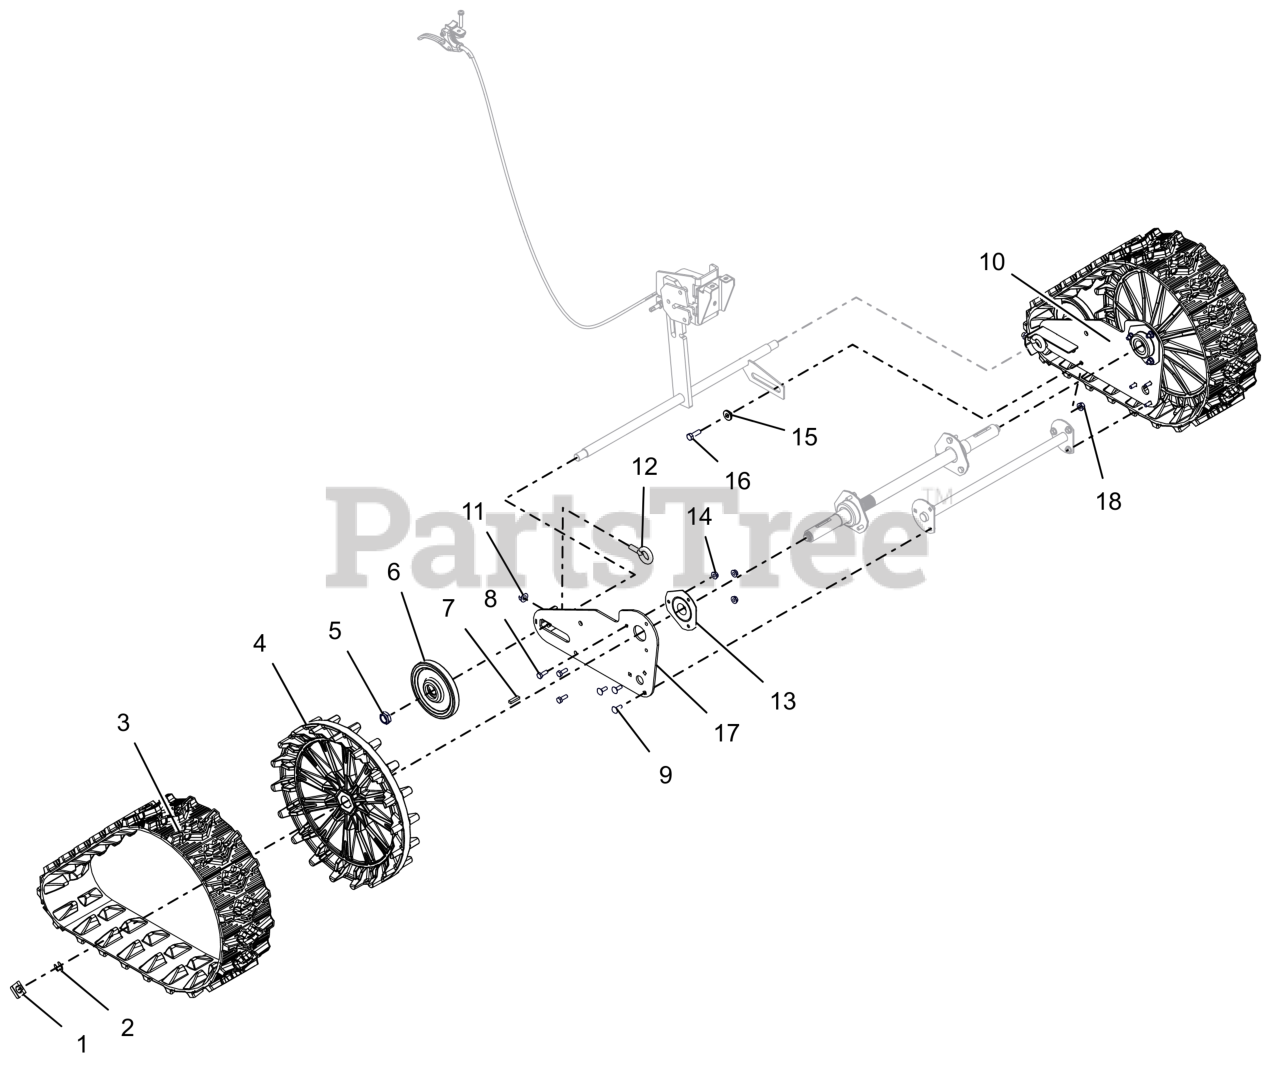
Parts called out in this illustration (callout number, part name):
1	CLIP, SNAP .625 DIA
2	RG-RTNG-EXT .625X.042
3	TRACK, RUBBER - 22 PITCHES
4	SPROCKET, LARGE TRACK DRIVE
5	NUT, NYL LK .625-18 ZCC
6	WHEEL, BOGIE - SINGLE BEARING
7	KEY-RECT .25X.188X1.00
8	BLT, HEX .25-20X.75 G5 ZCC
9	BLT, RHSN .25-20X.750 G5 ZCC
10	PLATE, SIDE-BWT LH WLDMT
11	NUT-LK-CTR-FLG .375-16 GF ZCC
12	BLT-EYE .375-16X.880 YWZC
13	BRG-FLG 1.003/1.000 3 BOLT
14	NUT-LK-TOP-FLG .250-20 GF ZCC
15	BSHG-FLG .325X.499X.3X.875
16	BLT,HEX .31-18X1.00 G5 ZCC
17	PLATE, SIDE-BWT RH WLDMT
18	NUT-LK-TOP-FLG .312-18 GF ZCC
